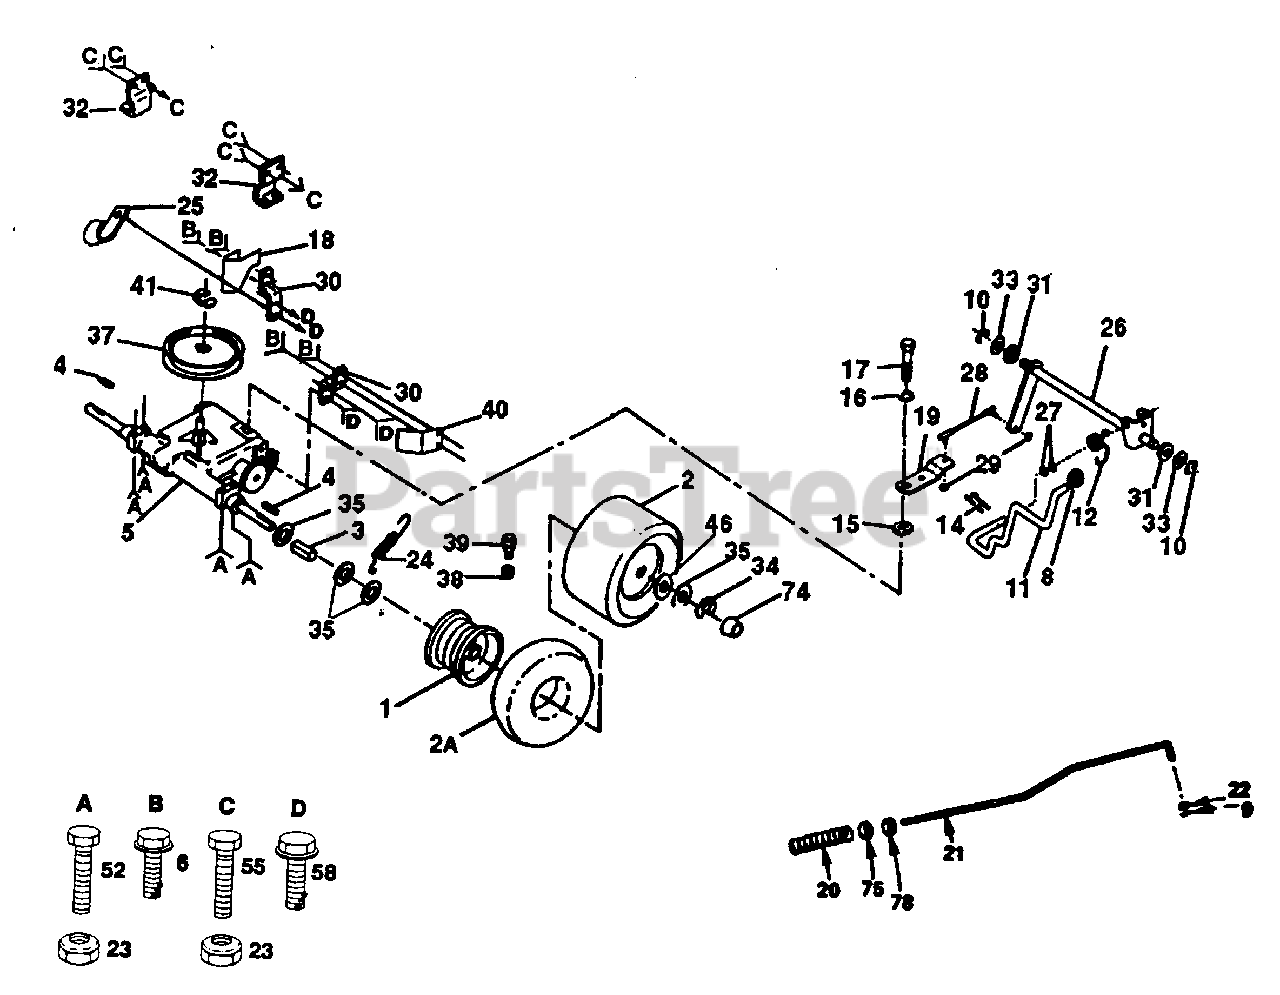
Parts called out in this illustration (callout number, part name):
1	Rim Assembly, Rear (AYP part number)
2	Tire (AYP part number)
2A	Tube, Tire (AYP part number)
3	Spacer, Split (AYP part number)
4	Key, Square 2.5 x .1845/.1865 (AYP part number)
5	Transaxle, 6 Speed, Foot Dana (AYP part number)
6	Screw, Hex Washer Head, Threaded Rolling 3/8-16 x 3/4 (AYP part number)
8	Knob, Control (AYP part number)
9	Pin, Cotter 1/8 x 3/4 (AYP part number)
11	Rod, Shifter (AYP part number)
12	Spring, Torsion (AYP part number)
14	Pin, Cotter 1/8 x 1 (AYP part number)
15	Washer, Shift Plate (AYP part number)
16	Washer 9/32 x 3/4 x 16 Gauge (AYP part number)
17	Bolt, Hex 1/4-28 x 3/4 Grade 8 (AYP part number)
18	Keeper, Belt, Transaxle, L.H. (AYP part number)
19	Arm, Shift (AYP part number)
20	Spring, Rod, Brake (AYP part number)
21	Rod, Brake (AYP part number)
22	Washer 13/32 x 13/16 x 16 Gauge (AYP part number)
23	Locknut 3/8-16
24	Spring, Brake Return (AYP part number)
25	Clip (AYP part number)
26	Shaft Assembly, Shifter (AYP part number)
27	Washer 17/32 x 3/4 x 16 Gauge (AYP part number)
28	Rod, Tie (AYP part number)
29	Nut 1/4-28 (AYP part number)
30	Strap, Torque (AYP part number)
31	Bushing, Pivot (AYP part number)
32	Bracket, Transaxle (AYP part number)
33	Washer .53 x 1.25 x .0598 (AYP part number)
34	E-Ring (AYP part number)
35	Washer 25/32 x 1-1/4 x 16 Gauge (AYP part number)
37	Pulley, Transaxle (AYP part number)
38	Cap, Valve (AYP part number)
39	Stem, Valve (AYP part number)
40	Keeper, Belt, Transaxle, R.H. (AYP part number)
41	Ring, Retainer (AYP part number)
46	Washer 25/32 x 1-5/8 x 16 Gauge (AYP part number)
52	Bolt, Hex 3/8-16 x 2-3/4 (AYP part number)
55	Bolt, Hex 3/8-16 x 3/4 (AYP part number)
58	Screw, Hex Washer Threaded, Rolling 5/16-18 UNC x 3/4 Type TT
74	Cap, Axle (AYP part number)
75	Locknut, Hex, Washer Insert 3/8-16 (AYP part number)
78	Nut, Hex, Jam 3/8-16 (AYP part number)
